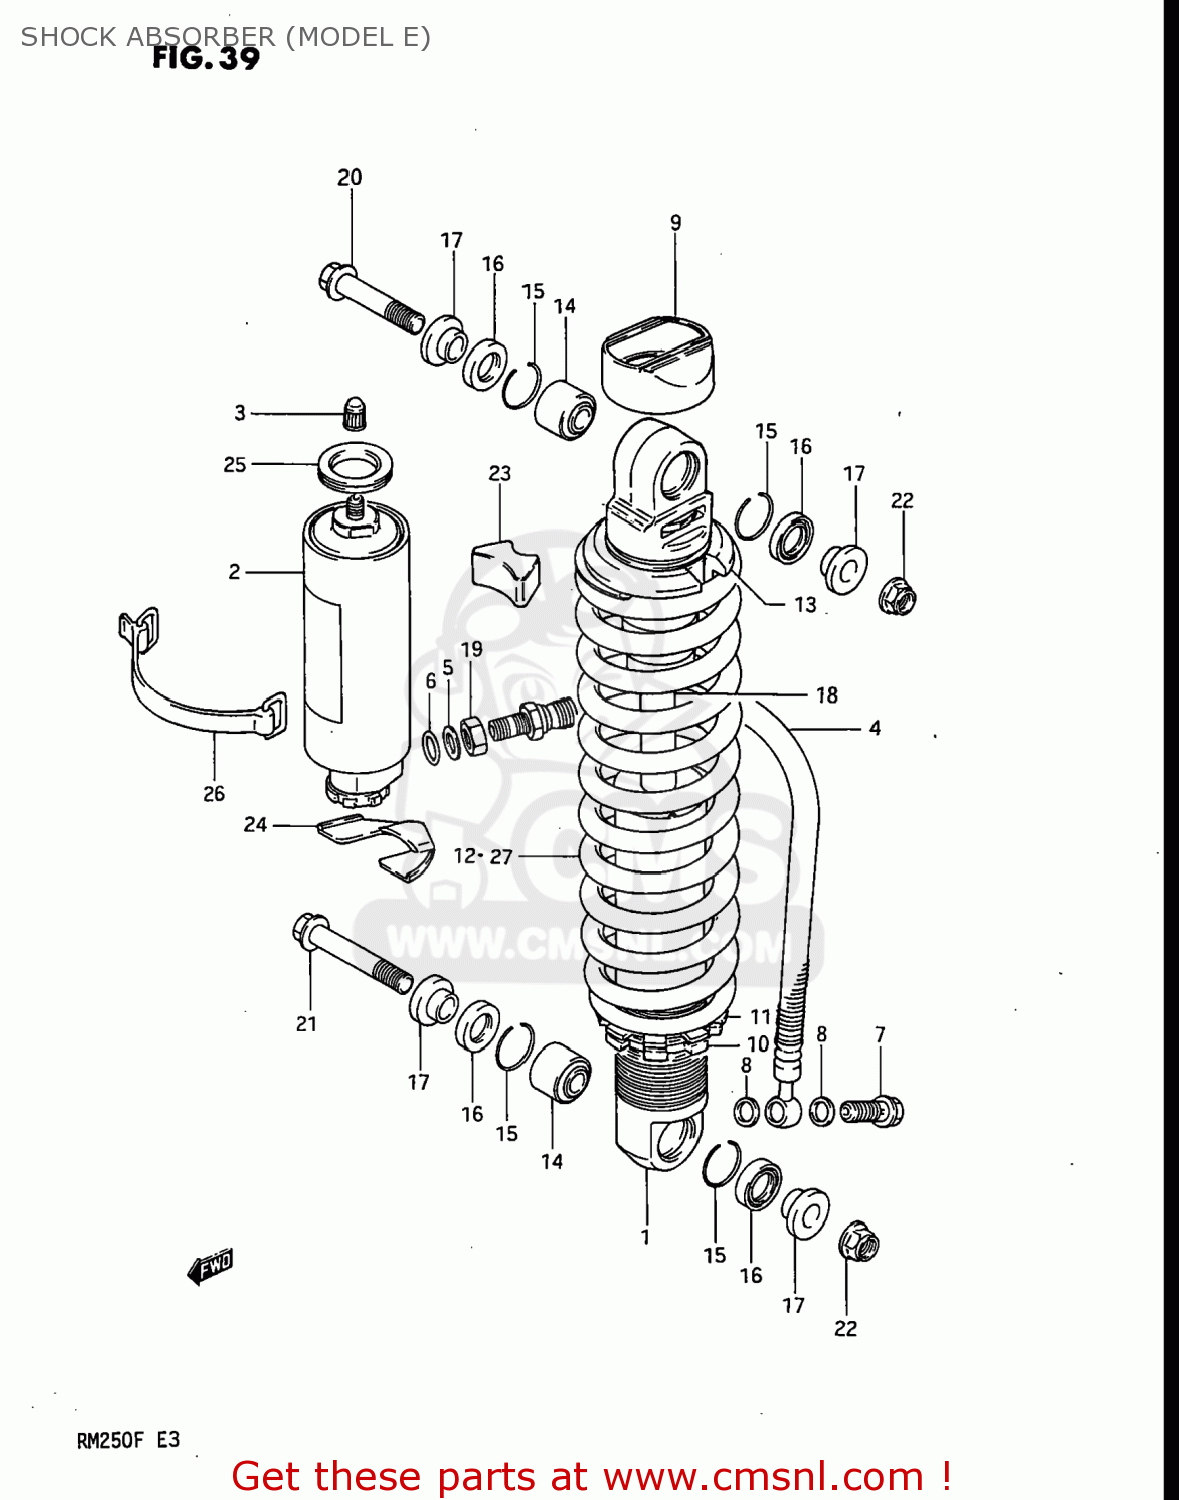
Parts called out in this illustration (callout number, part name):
1	ABSORBER ASSEMBLY,REAR SHOCK
2	RESERVE TANK,REAR SHOCK
3	CAP
4	HOSE,REAR SHOCK ABSORBER
5	WASHER,REAR SHOCK HOSE
6	O-RING,RESERVE TANK
7	BOLT,REAR SHOCK ABSORBER
8	GASKET (NAS)
9	CAP
10	GUIDE,REAR SHOCK ABSORBER SPRING
11	GUIDE,SPRING
12	SPRING,REAR SHOCK
13	GUIDE,REAR SHOCK ABSORBER SPRING
14	BEARING,REAR SHOCK ABSORBER
15	RING
16	SEAL,DUST
17	SPACER
18	ROD,PISTON
19	NUT 12MM
20	BOLT,REAR SHOCK ABSORBER
21	BOLT(10X52)
22	NUT
23	CUSHION,RESERVOIR TANK
24	CUSHION,RESERVOIR TANK
25	CUSHION,RESERVOIR TANK
26	BAND
27	SPRING
